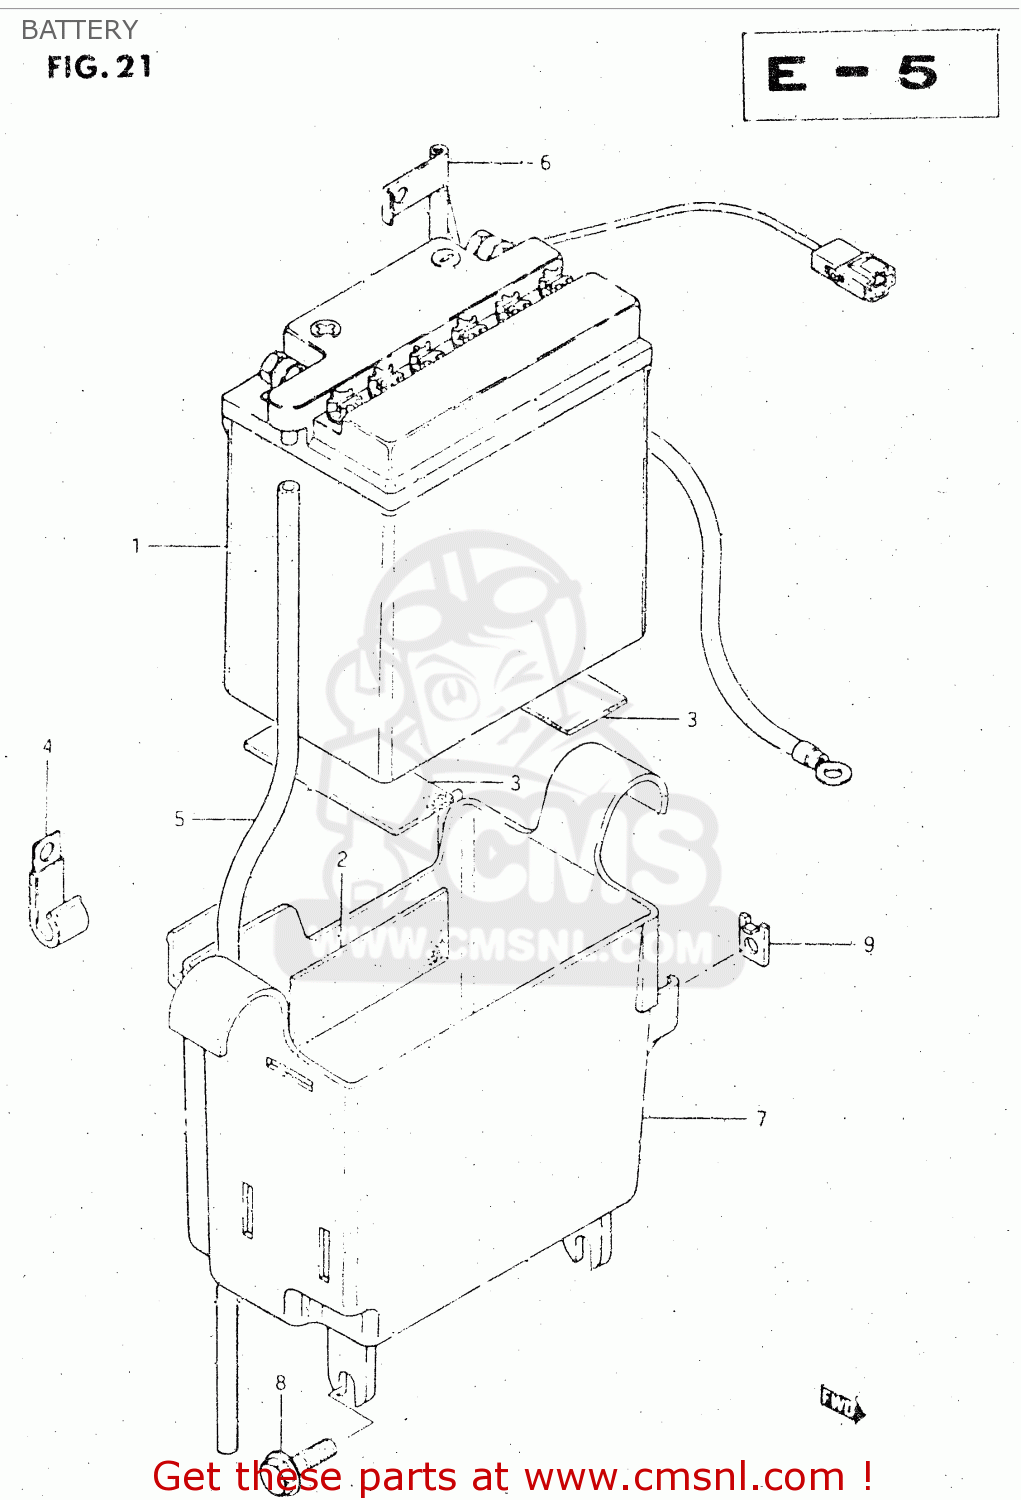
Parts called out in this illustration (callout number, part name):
1	BATTERY(YB10L-B,12V12AH)
2	PROTECTOR(30X80X2)
3	PROTECTOR,20X9
4	CLAMP
5	HOSE,BATTERY EXHAUST
6	WIRE,STARTER MOTOR LEAD
7	HOLDER,BATTERY
8	BOLT
9	WASHER,IGNITER
